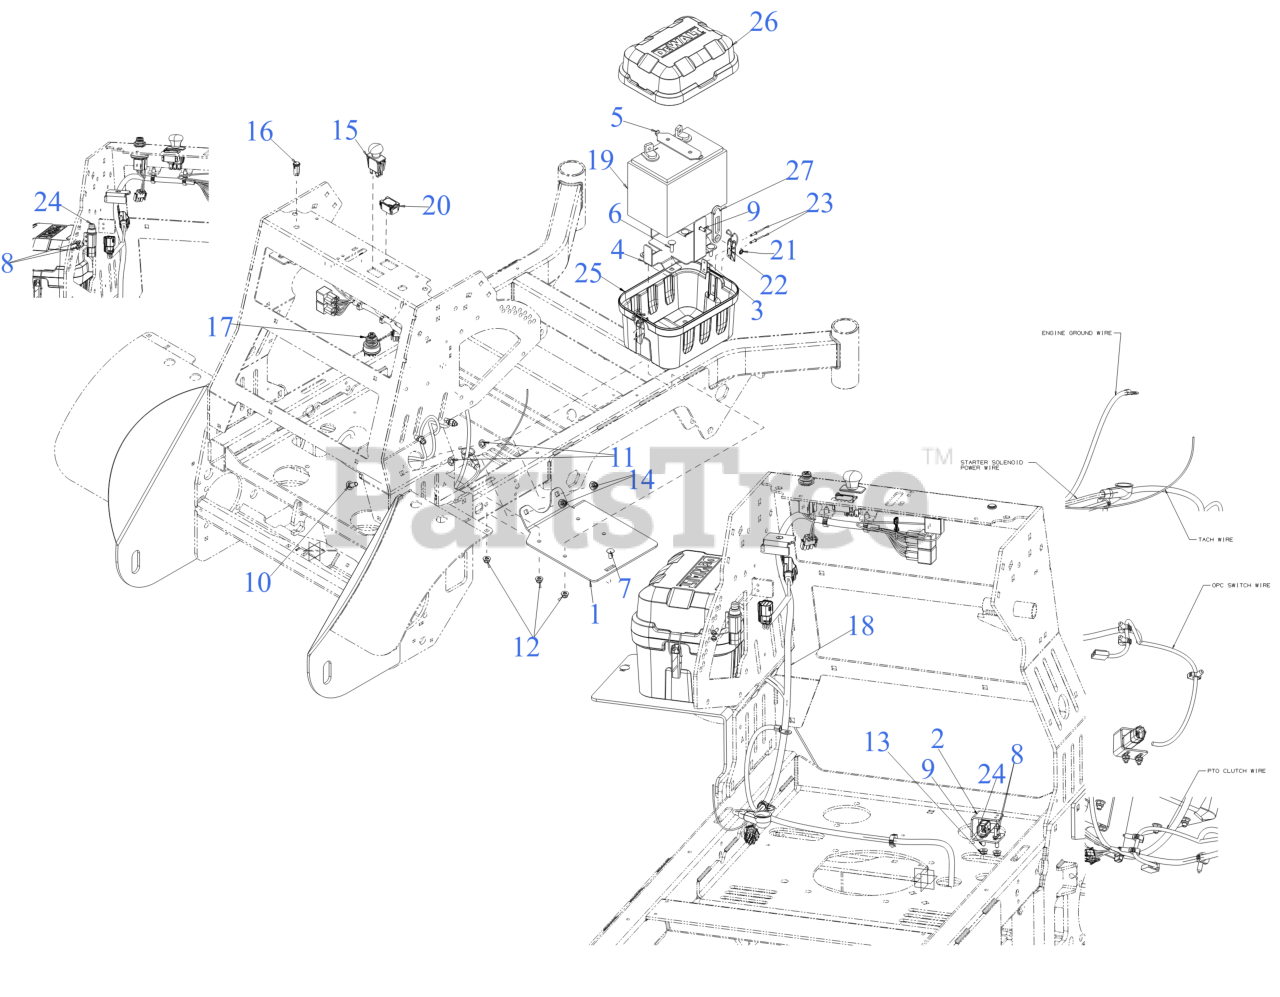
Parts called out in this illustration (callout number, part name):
1	BATTERY MOUNT BRACKET
2	OPC MOUNT BRACKET
3	BACK CLIP PLATE
4	BATTERY MOUNT
5	BATTERY STRAP
6	CARRIAGE BOLT 5/16-18 x 1.00
7	CARRIAGE BOLT 5/16-18 x .75
8	SCREW (10-24X.75:PH:TAP:T25:GR5)
9	SCREW 1/4-20 x .75 GR5
10	CARRIAGE BOLT 3/8-16 x 1.00 GR5
11	PUSH NUT
12	FLANGE LOCK NUT 5/16-18
13	FLANGE LOCK NUT
15	PTO SWITCH (BLACK KNOB) TEXT SYM
16	INDICATOR LIGHT-RED
17	KEY SWITCH
18	HARNESS (EFI KAW)
19	BATTERY (230 CCA AGM U1-280)
20	HOUR METER
21	RETAINER-BOLT .25ID x .50OD
23	RIVOT
24	SEALED PLUNGER SWITCH
25	BATTERY BOX (LOWER)
26	BATTERY BOX (UPPER)
27	COVER STRAP 2.50 LONG
